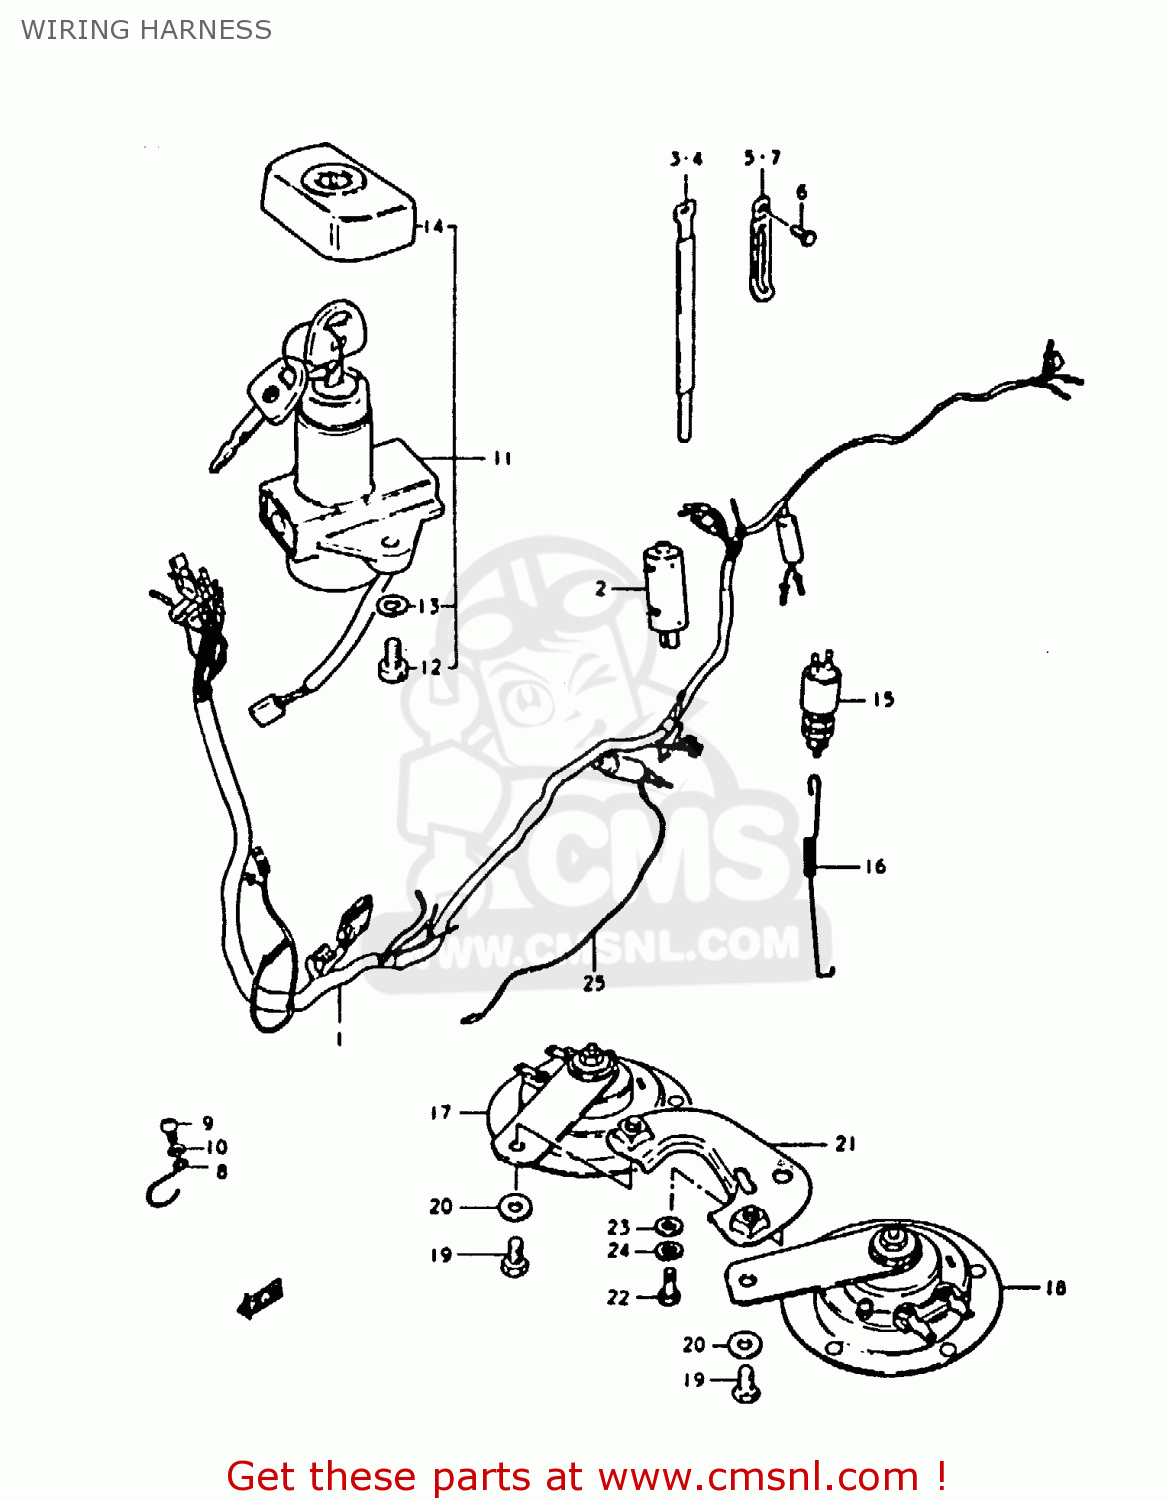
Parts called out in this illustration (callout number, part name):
1	WIRING HARNESS
2	BOOT,WIRING HARNESS
3	CLAMP(L:120)
4	CLAMP
5	CLAMP
6	BOLT
7	CLAMP
8	GUIDE,WIRING HARNESS
9	SCREW 6X12
10	WASHER 6MM
11	LOCK ASSEMBLY,STEERING
12	BOLT
13	LOCK WASHER
14	CAP,IGNITION SWITCH
15	SWITCH ASSY,BRAKE LAMP
16	SPRING
17	HORN ASSY
18	HORN ASSEMBLY,HIGH PITCH
19	BOLT 8X12
20	WASHER
21	BRACKET,HORN
22	BOLT
23	WASHER
24	LOCK WASHER
25	LEAD WIRE, OIL PRESSURE SWITCH
